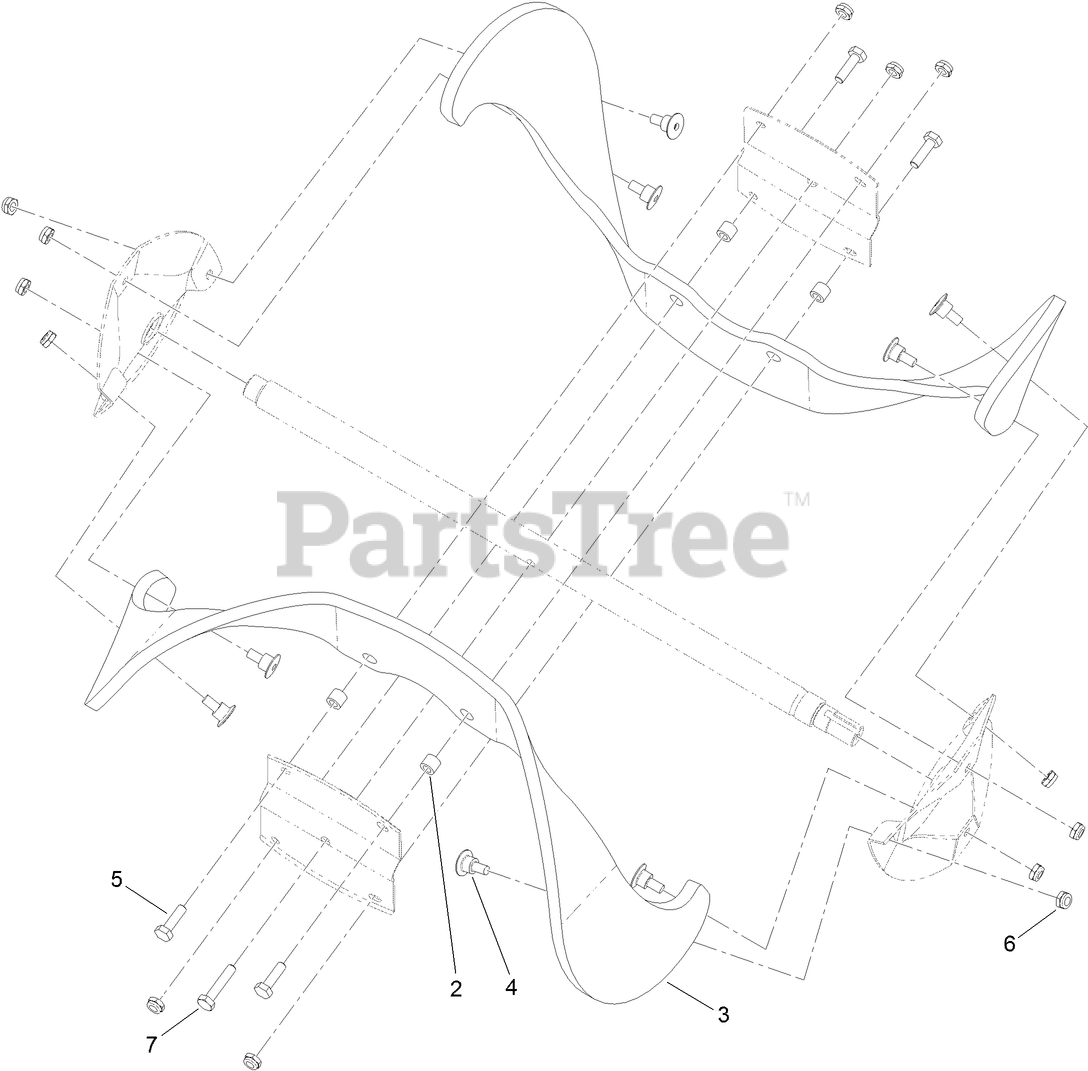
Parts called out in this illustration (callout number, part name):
2	SPACER
3	BLADE-ROTOR
5	SCREW-HH
6	NUT-LOCK, NI
7	SCREW-HH
